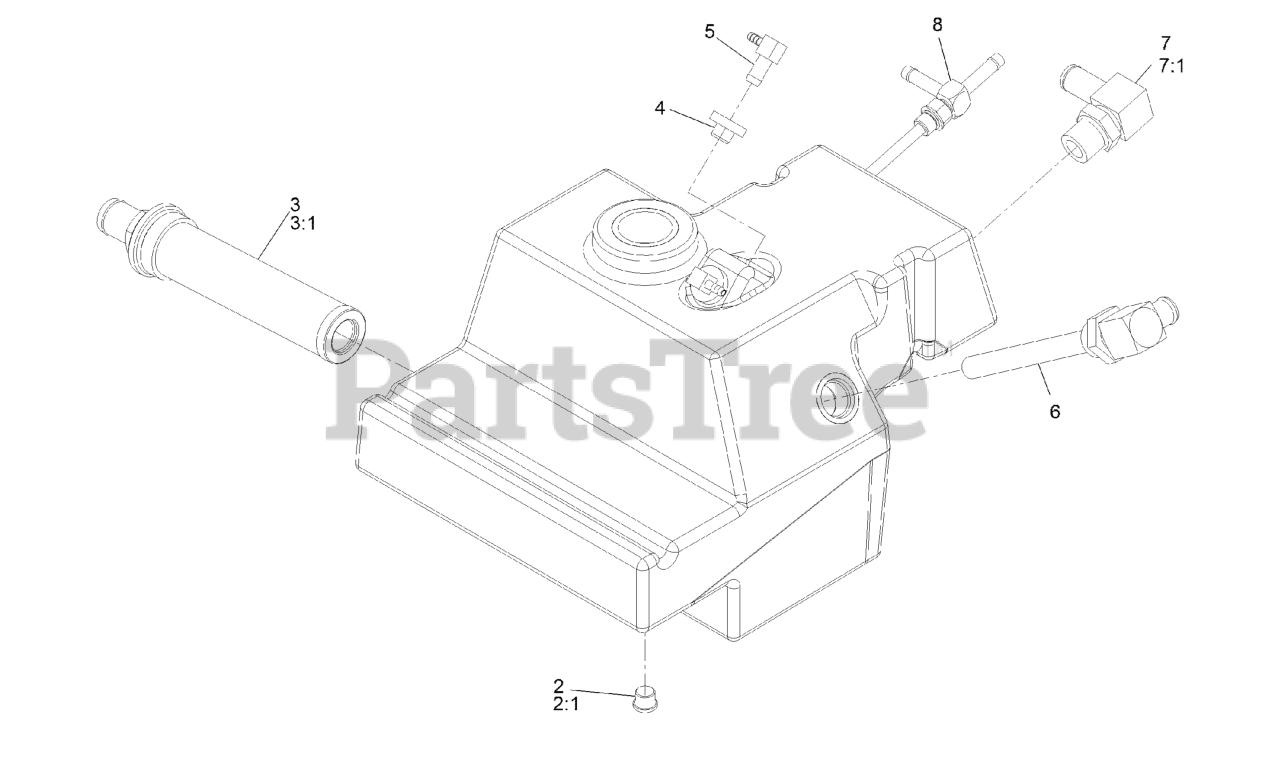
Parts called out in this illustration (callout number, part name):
2	PLUG-HEX, HOLLOW
2:1	O-RING
3	TANK STRAINER ASM
4	BUSHING
5	FITTING-ELBOW, 90 DEG
6	Fitting-Standpipe
7	FITTING-ELBOW, 90
7:1	O-RING
8	FITTING-TEE, DROP TUBE
